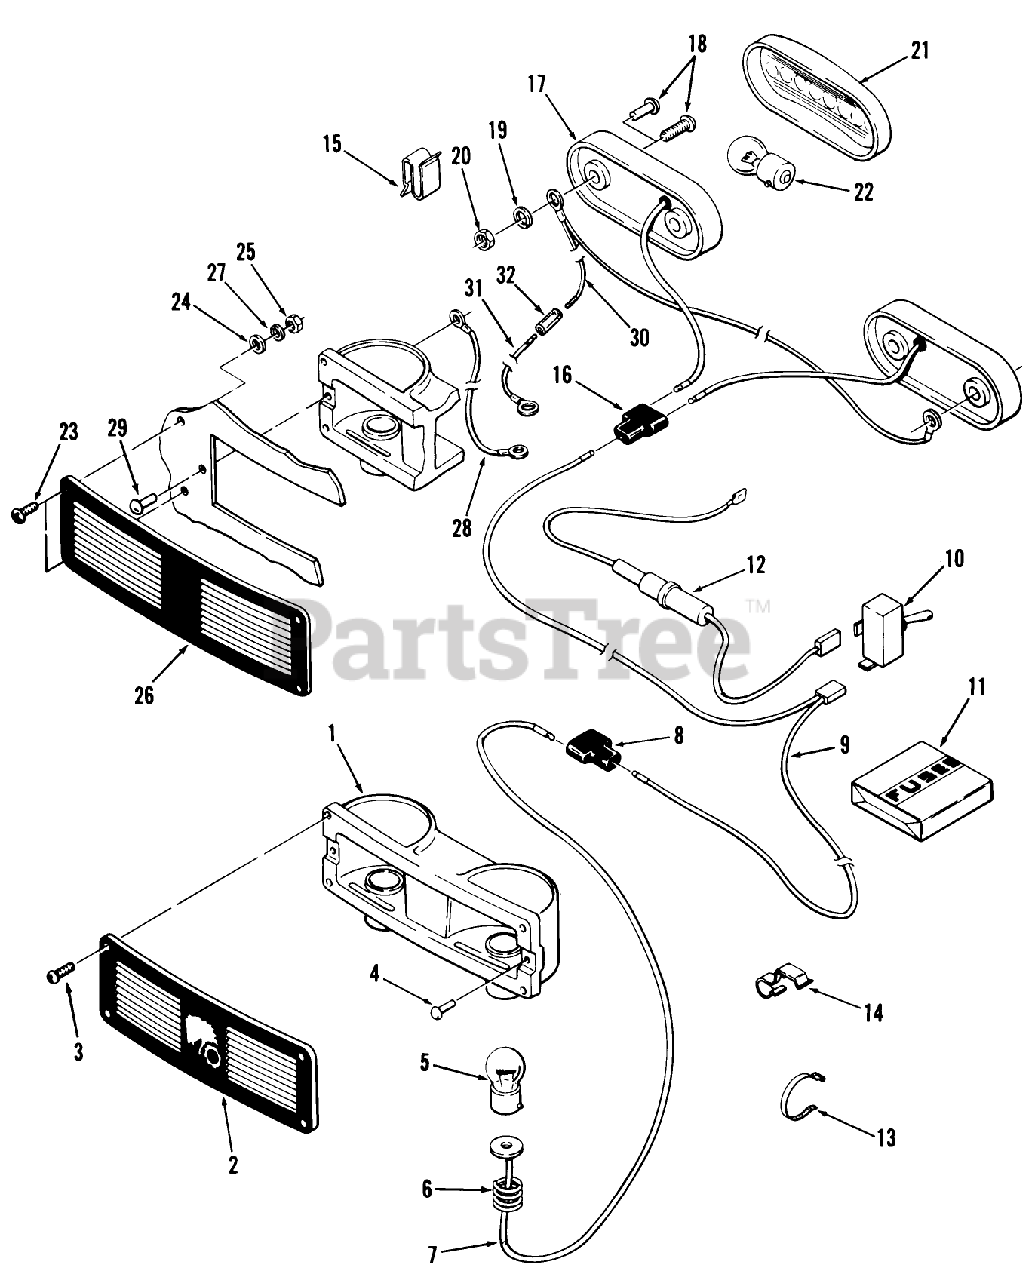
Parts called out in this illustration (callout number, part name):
5	BULB
6	SPRING
10	SWITCH-LIGHTS
22	Bulb
